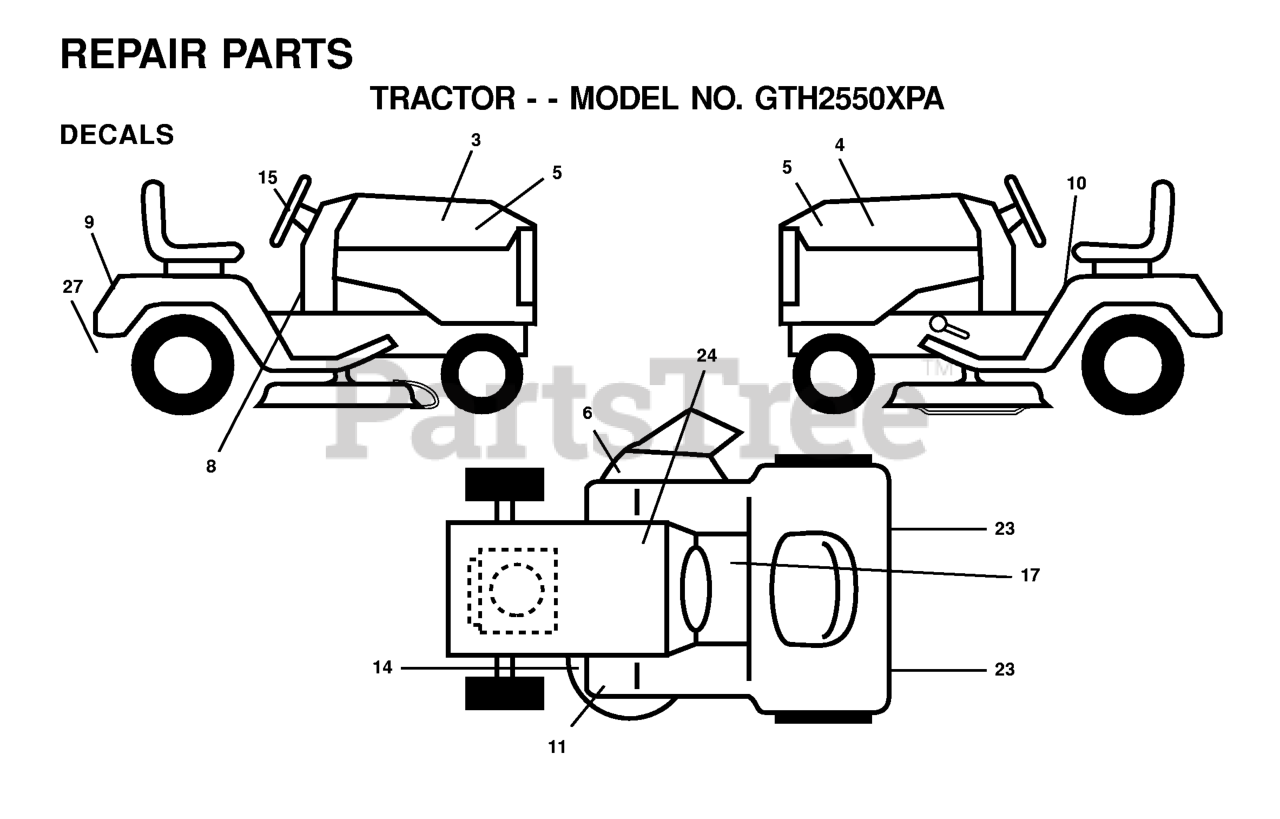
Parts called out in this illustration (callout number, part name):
5	DECAL HOOD
6	DECAL.WARN.KEEP.HAND.AWAY
8	DECAL, DASH
9	DECAL, FENDER
10	DECAL FENDER DANGER
14	DECAL V-BELT SCHEMATIC
15	DECAL.WHEEL.STEERING.HUSQ.PERM
17	DECAL PARK BRAKE
23	REFLECTOR-TAIL YT
24	DECAL BTRY SYMBOLS
27	DECAL.BYPASS.FENDER.CRD.LT.YT
